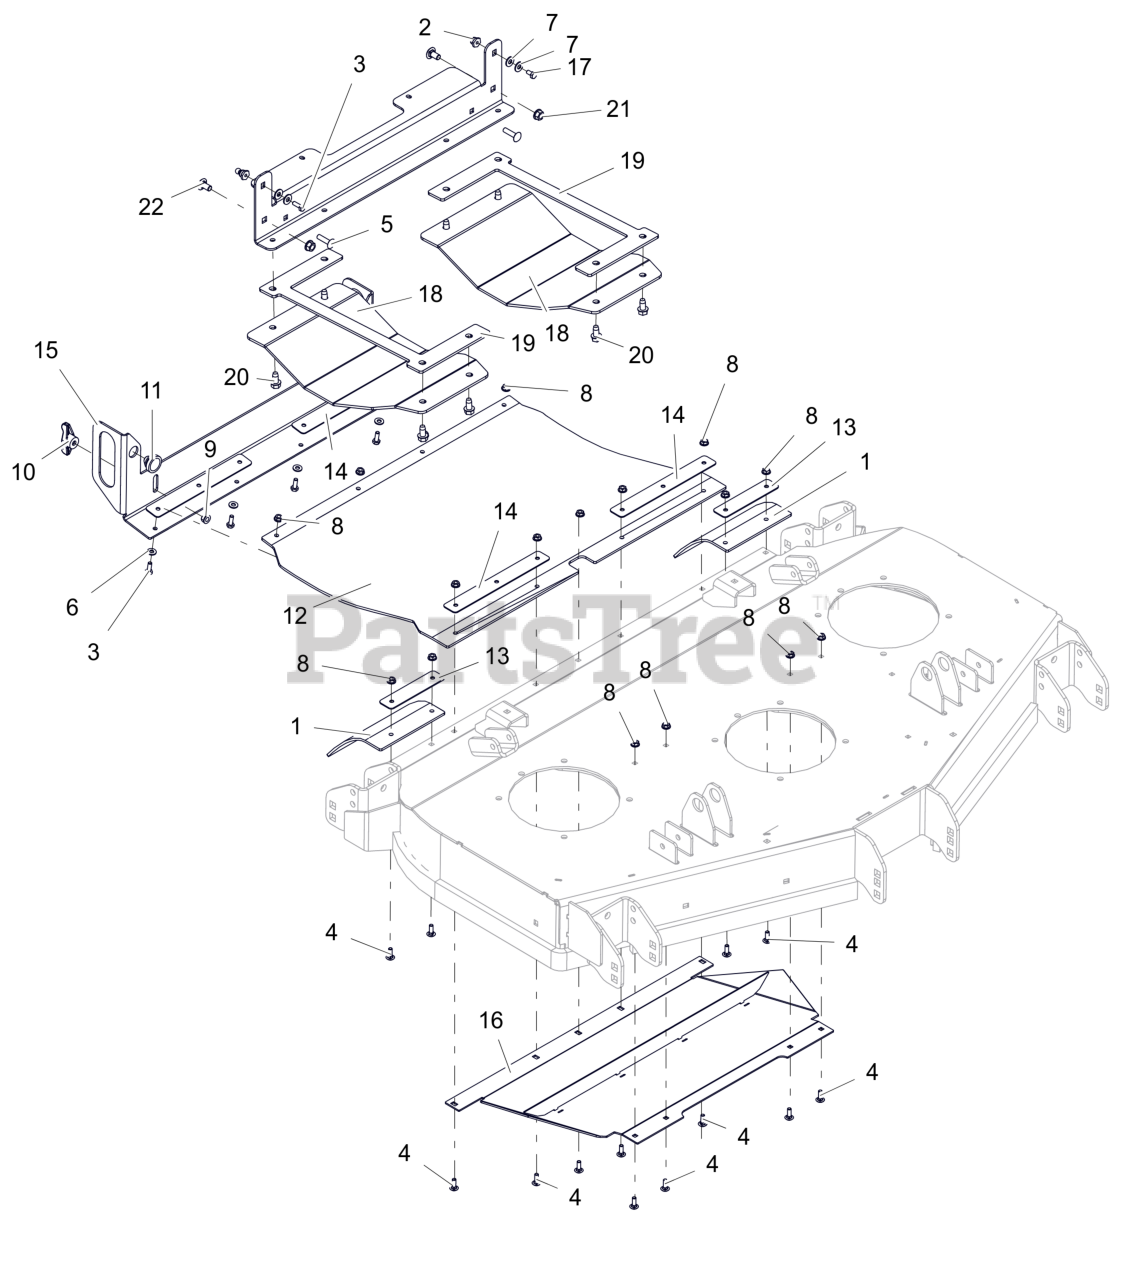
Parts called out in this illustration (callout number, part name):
1	FLAP, REAR DISCHARGE 48" TIRE
2	STUD, BALL FEMALE .250-20 THREAD
3	BLT, HEX .25-20X.75 G5 ZCC
4	BLT, RHSN .25-20X.750 G5 ZCC
5	BTL,RHSSN .313-18 X 1.25 G5 ZCC
6	WSHR,FLT .281X.625X.065 ZCC
7	WSHR, FLT .312X.734X.065 ZCC
8	NUT-LK-CTR-FLG .25-20 ZC120
9	NUT,LK-CTR-FLG .31-18 GF ZCC
10	KNOB,WING .31-18 UNC NYL/TALC
11	COUPLING, RUBBER PUSH-IN
12	CHUTE- 52" REAER DISCHARGE
13	PLATE- 52" TIRE CHUTE MTG
14	PLATE, CHUTE MTG (BLACK)
15	HANDLE, CHUTE MOUNTING (RED)
16	WLDMT, DEFLECTOR BAFFLE (RED)
17	BLT,HEX .25-20X.50 G5 ZCC
18	PLATE, SKID (BLACK)
19	PLATE, SKID TENSION (BLACK)
20	SCR,TAP .375-16X.75 HWH TR ZCC
21	NUT-LK-CTR-FLG .375-16 GF ZCC
22	BLT, RHSSN .38-16X.75 G5 ZCC
